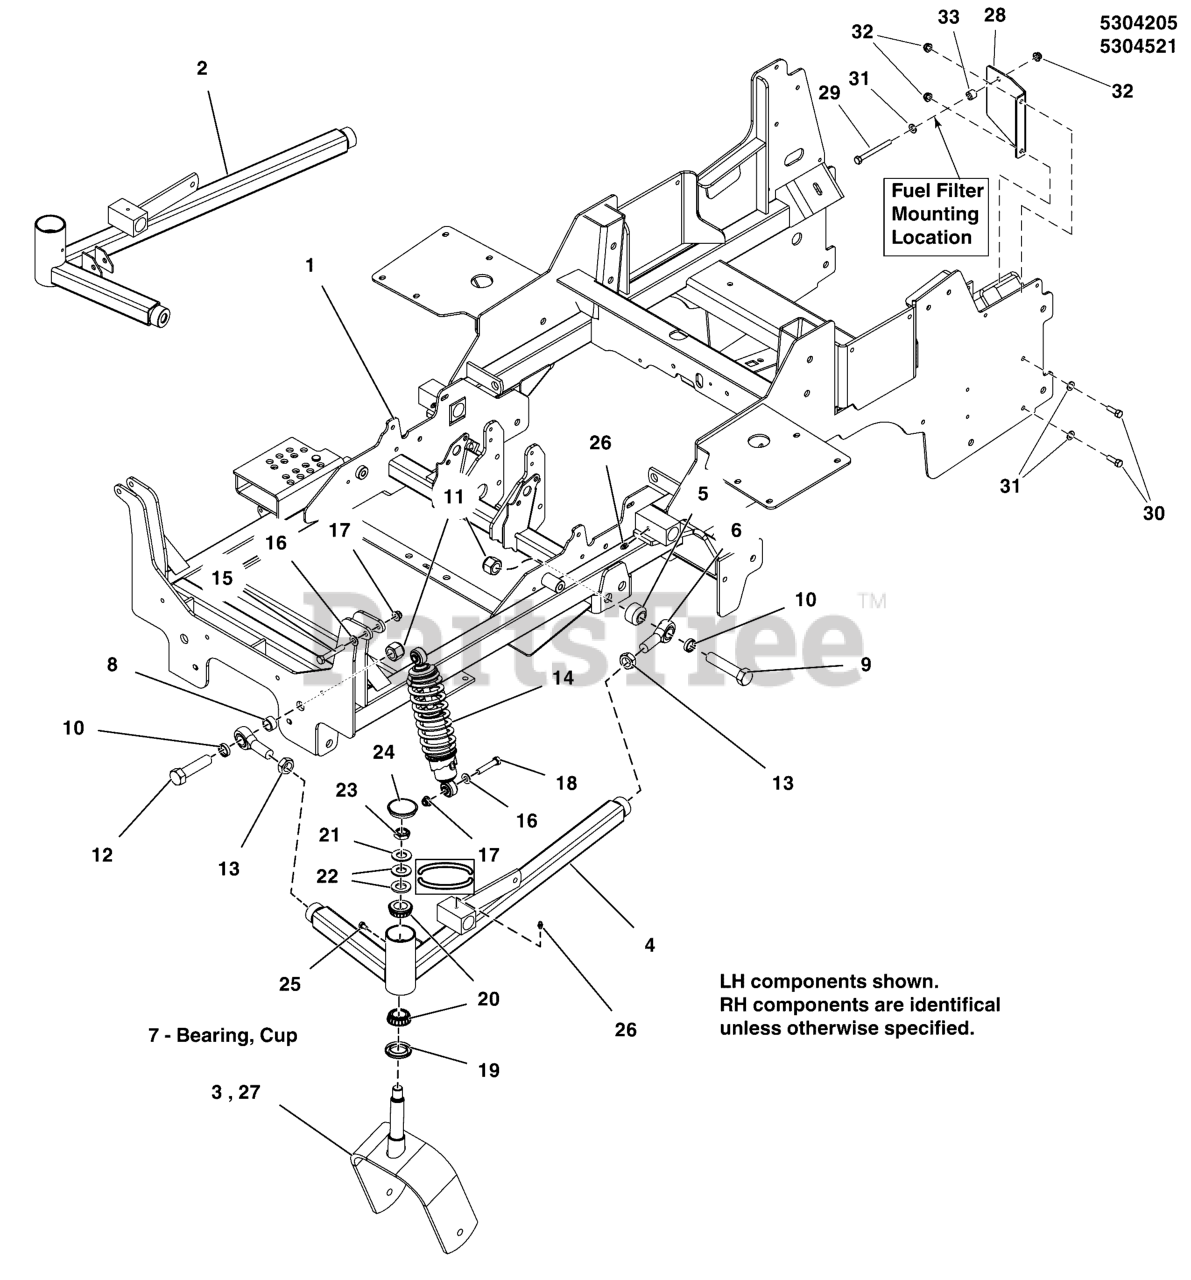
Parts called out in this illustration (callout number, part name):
1	FRAME
2	WELD, FRONT A-ARM, RH, IS2600Z - RED
3	WELD, CASTER YOKE - RED
4	WELD, FRONT A-ARM, LH, IS2600Z - RED
5	SPACER, .75 X 1.50 X 1.00, CZ
6	BALL JOINT, 3/4-16, MALE
7	BEARING CUP
8	SPACER, .76 X 1.00 X .50, CZ
9	BOLT, 3/4-16 X 3-1/2 GD8 CZ
10	SPACER, .76 X 1.00 X .25
11	NUT, 3/4-16 HEX NYLON LOCK
12	BOLT-3/4-16 X 3 GD8 CZ
13	NUT, 3/4-16 HEX JAM
14	SHOCK / SPRING ASSEMBLY, OE22375
15	BOLT, 3/8-16 X 2-1/4" GD5 CZ
16	WASHER, 3/8 SAE
17	NUT, 3/8-16 HEX NYLOCK FLANGE
18	BOLT, 3/8-16 X 2, GD5, CZ
19	SEAL, GREASE
20	BEARING, TAPERED ROLLER, 1
21	WASHER, 3/4 SAE
22	WASHER, BELLEVILLE - 1.500 X .755
23	NUT, 3/4-16, HEX JAM NYLON LOCK
24	CAP, GREASE, LOW PROFILE
25	BOLT, 1/4-28 X 1/2, GD5 CZ
26	GREASE FITTING, 1/4-28 STRAIGHT
27	WELD, CASTER YOKE - RED
28	PLATE, FUEL FILTER TAB - BLK
29	BOLT, 5/16-18 X 3-1/4 GD5
30	BOLT, 5/16-18 X 1" GRD5 YZ
31	WASHER, 5/16" SAE
32	NUT, 5/16-18 HEX NYLOCK FLANGE NUT
33	SPACER, .33 X .63 X .50, CZ
